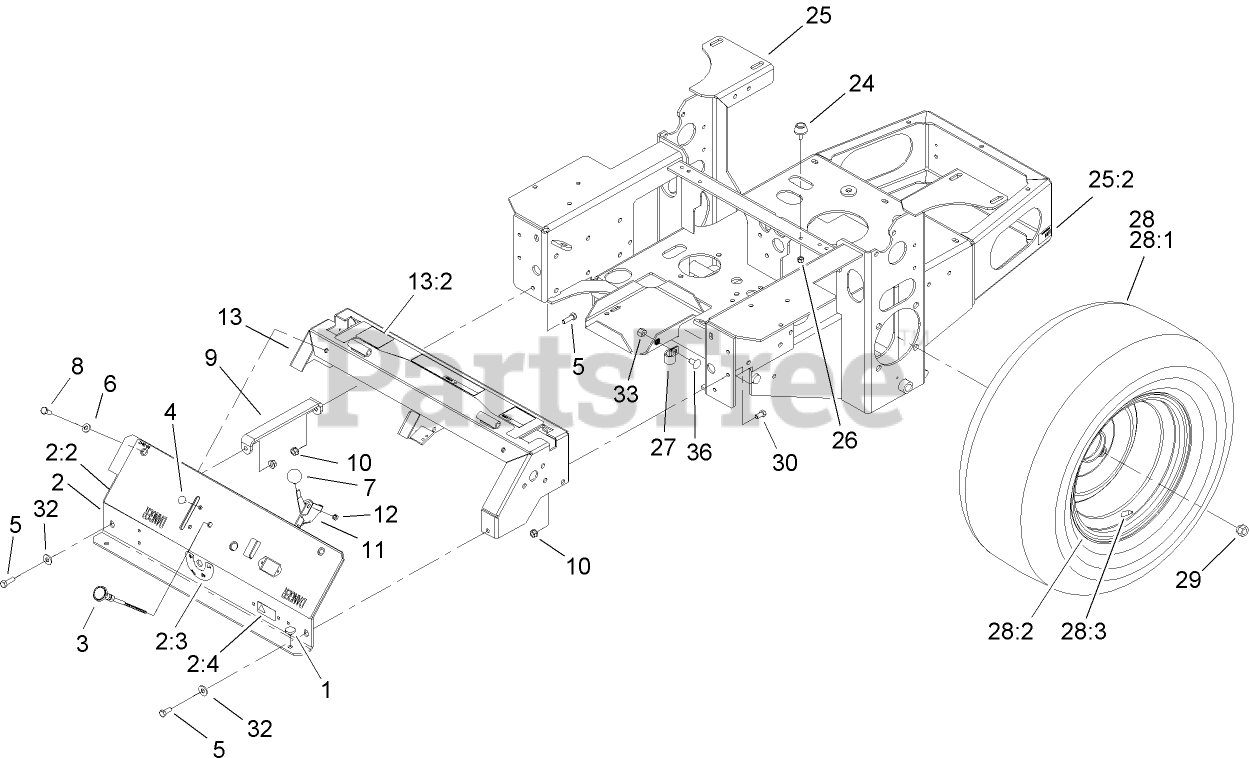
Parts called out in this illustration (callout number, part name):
1	BUMPER
2	CONSOLE ASM
2:2	DECAL-PANEL, CONTROL
2:3	DECAL-VALVE, FUEL
2:4	DECAL-PROTECTION, EAR
3	CONTROL-CHOKE
4	BOLT-CARR
5	SCREW-HH
6	WASHER-PLAIN
7	KNOB-BALL
8	SCREW-HH
9	BRACKET
10	NUT-HF
11	THROTTLE CABLE ASM
12	NUT-LOCK, NI
13	CONSOLE FRAME ASM
13:2	DECAL-CONSOLE, TOP
24	BUMPER
25	MAIN FRAME ASM
25:2	DECAL-SURFACE, HOT
26	NUT-LOCK, NI
27	CLIP-LOOM
28	WHEEL AND TIRE ASM
28:1	TIRE
28:3	STEM-VALVE
29	NUT-LUG
30	SCREW-HH
32	WASHER-FLAT
33	NUT-LOCK, NI
36	SCREW-CARR
